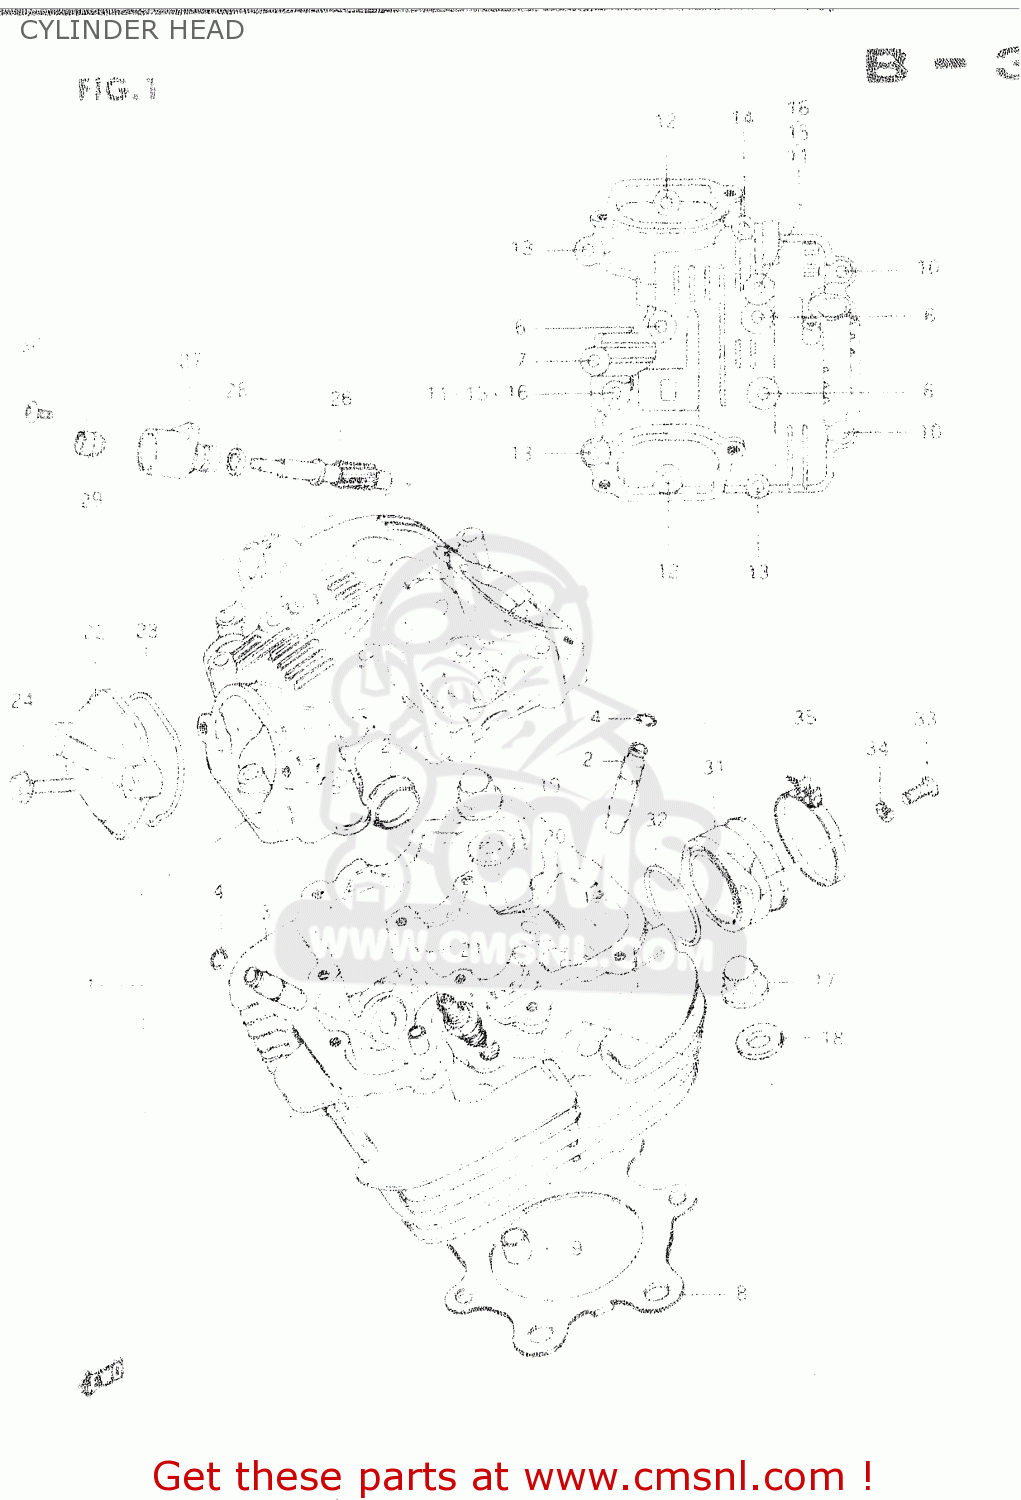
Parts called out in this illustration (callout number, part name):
1	HEAD ASSEMBLY,CYLINDER
2	GUIDE,INTAKE VALVE
3	GUIDE,VALVE
4	RING,SNAP
5	PIN(6.2X8X11)
6	BOLT ,6X60
7	BOLT 6X30
8	GASKET,CYLINDER HEAD (NAS)
9	PIN
10	BOLT
11	BOLT (6X30)
12	BOLT 6X30
13	BOLT (6X45)
14	BOLT ,6X60
15	NUT
16	WASHER
17	NUT
18	WASHER (10.5X22X2.3)
19	NUT
20	GASKET(10.5X22X2) (NAS)
21	SPARK PLUG D8EA
22	CAP,INSPECTION
23	O RING(D:2.4,ID:23)
24	BOLT
25	PLUG(OD:30)
26	GEAR,TACHOMETER DRIVEN
27	SLEEVE,TACHOMETER DRIVE GEAR
28	SEAL,TACHOMETER DRIVEN
29	SEAL,OIL(5X12X8)
30	SCREW(5X12)
31	PIPE,INTAKE
32	O-RING (D:2.4 ID:39.7)
33	SCREW
34	LOCK WASHER
35	CLAMP
